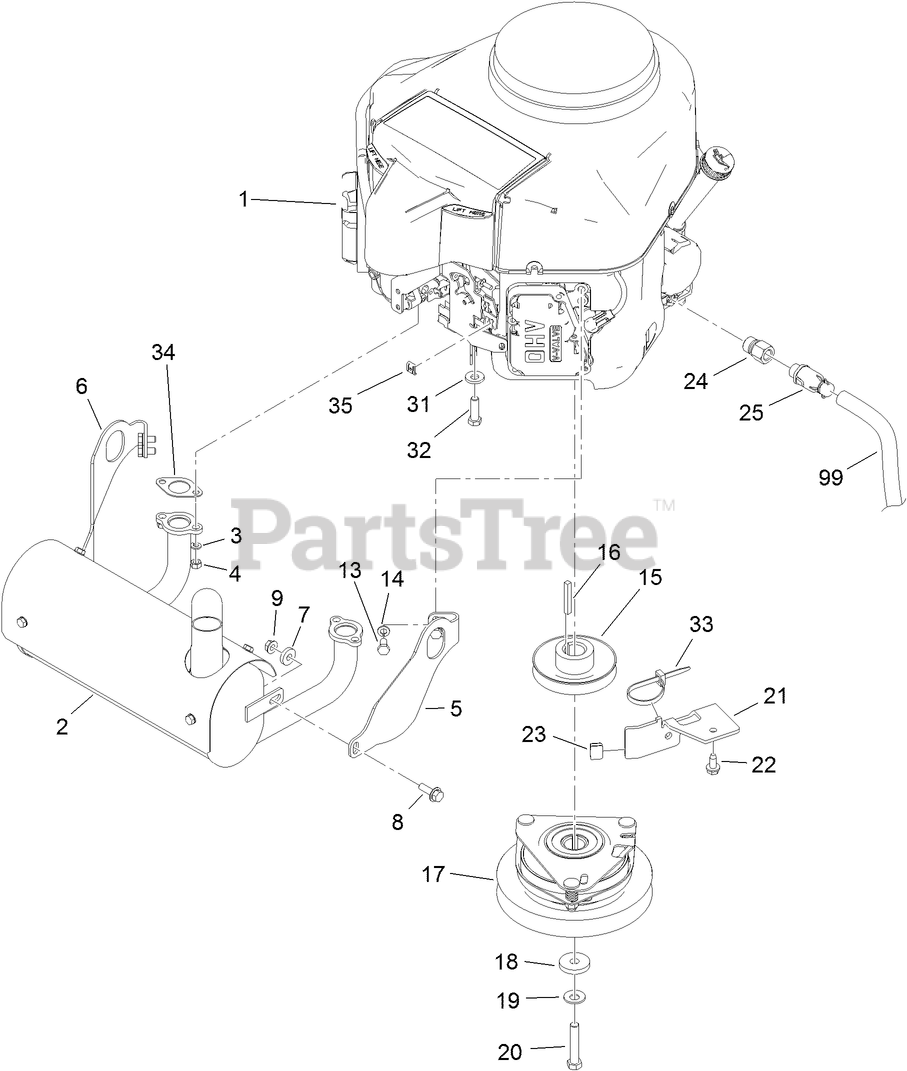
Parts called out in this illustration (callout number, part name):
2	MUFFLER
3	WASHER-LOCK
5	BRACKET-MUFFLER MOUNT, LH
6	BRACKET-MUFFLER MOUNT, RH
7	SPACER
8	SCREW-HHF
9	NUT-HF
13	SCREW-HH
14	WASHER-LOCK
15	PULLEY
16	KEY-SQUARE
17	CLUTCH / BRAKE ASM
18	WASHER
19	WASHER-SPRING
20	SCREW-HH
21	BRACKET-CLUTCH STOP
22	SCREW-HWHTF
23	BUMPER
24	Adapter
25	VALVE-DRAIN, OIL
31	WASHER-BELLEVILLE
32	SCREW-HH
33	TIE-CABLE
34	GASKET-EXHAUST
35	CLAMP-CABLE
99	HOSE-DRAIN, OIL
